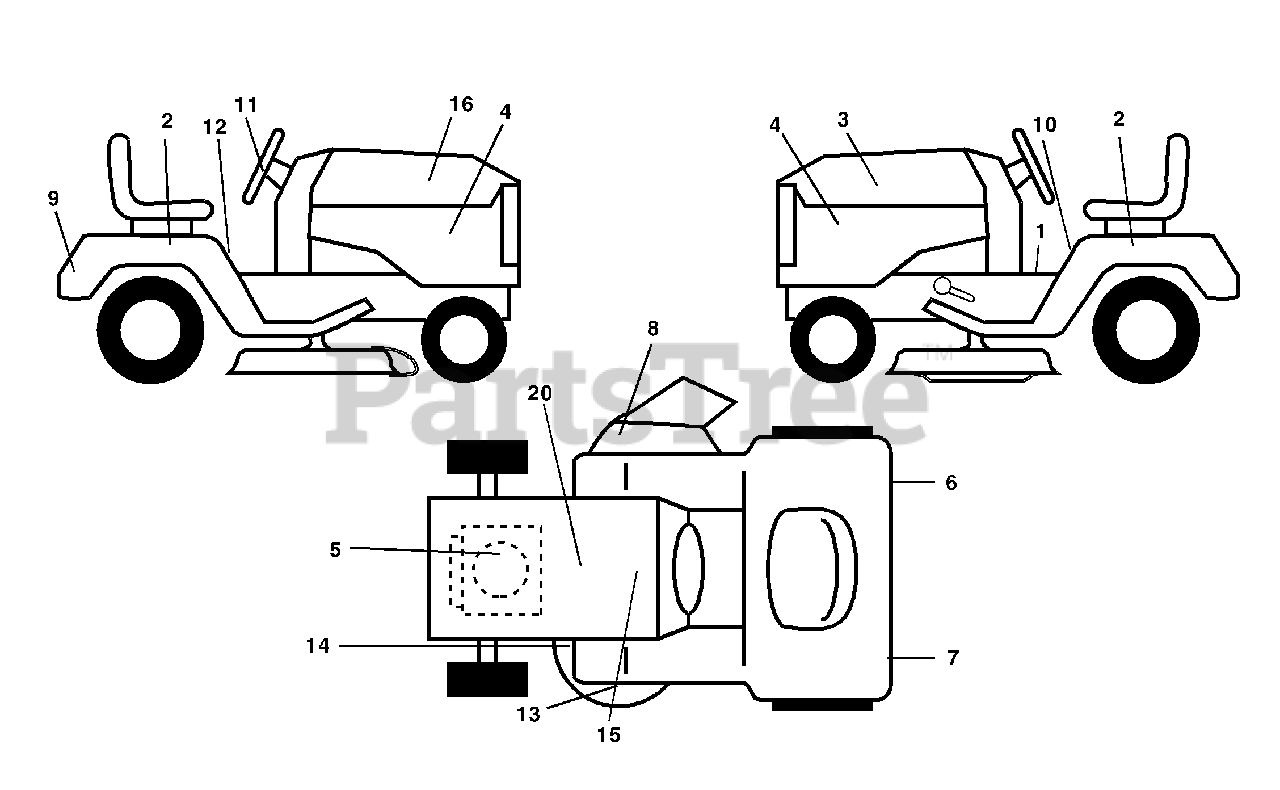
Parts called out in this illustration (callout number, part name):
1	Decal Dash
2	Decal Fender Auto
3	Decal Hood LH
4	Decal Side Panel
5	Decal HP Engine
6	Decal Reflector Rh
7	Decal Reflector Lh
8	Decal Warning Mower
9	Decal Fender Logo
10	Decal Fender Danger E/F
11	Decal Ins Strg Whl
12	Decal Fender Oper Cruise
13	Decal Deck Caution
14	Decal V-Belt Schematic
15	Decal Final
16	Decal Hood Rh
20	Decal Bat Dan/Psn
